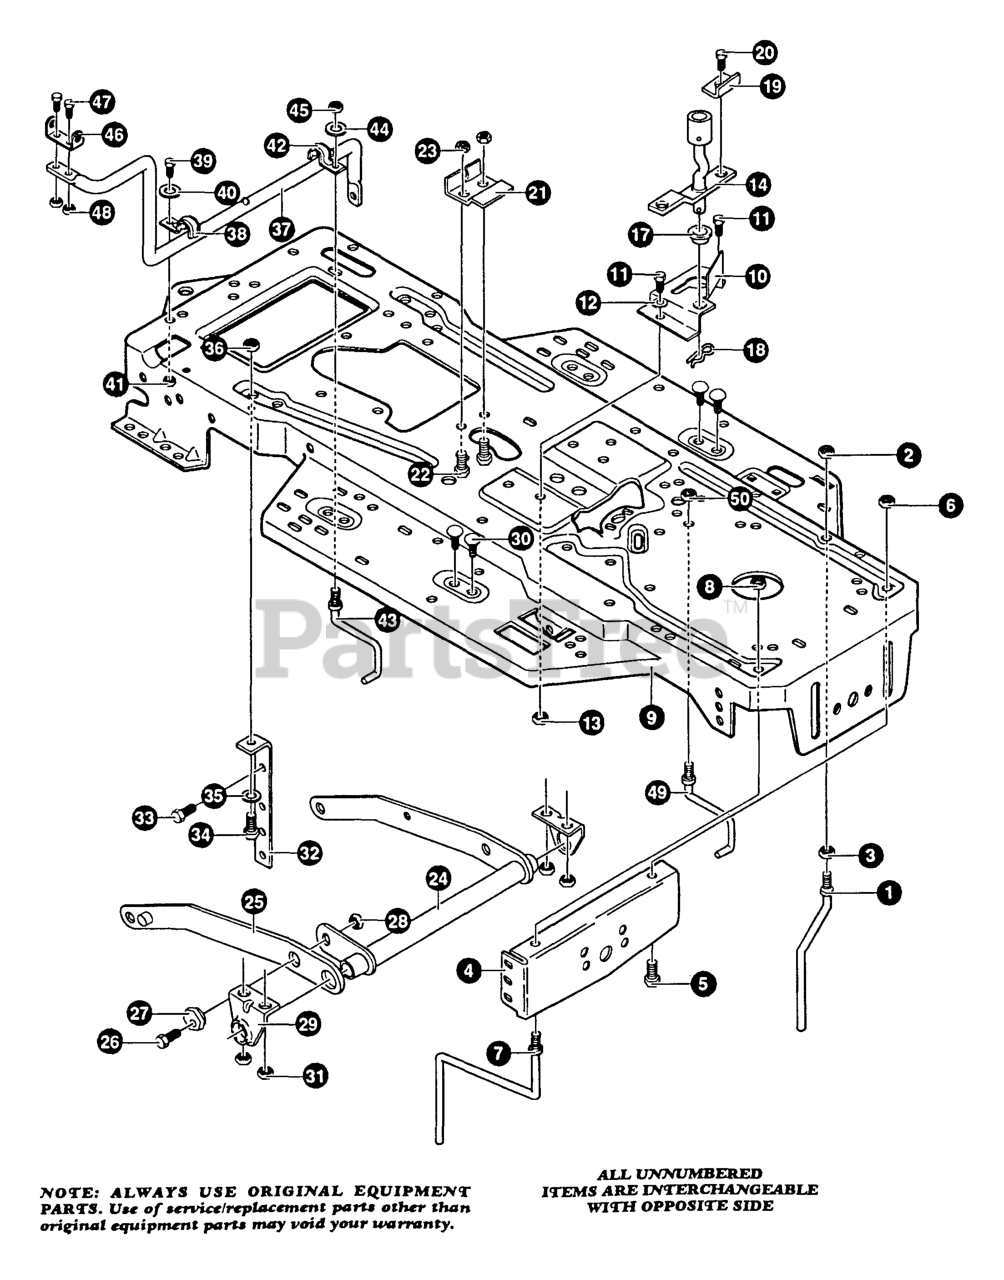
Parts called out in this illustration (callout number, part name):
1	GUIDE, BELT
4	BRACKET, AXLE
5	SCREW
7	GUIDE, BELT
9	FRAME, MAIN
10	BRACKET, CLUTCH
12	WASHER
14	ASSEMBLY, CLUTCH
17	BEARING
19	BRACKET, SWITCH
20	SCREW
21	BRACKET, CABLE
24	LIFT ASSY, LH
25	LIFT ASSY, RH
29	BRACKET
32	BRKT, STABILIZER
33	SCREW
35	WASHER
37	LEVER, SHIFT-LOWER
38	CLIP- SHIFT LEVER
39	SCREW
40	WASHER
43	GUIDE, BELT
44	WASHER
46	BRACKET, SHIFT LEVER
49	GUIDE, BELT, RH
